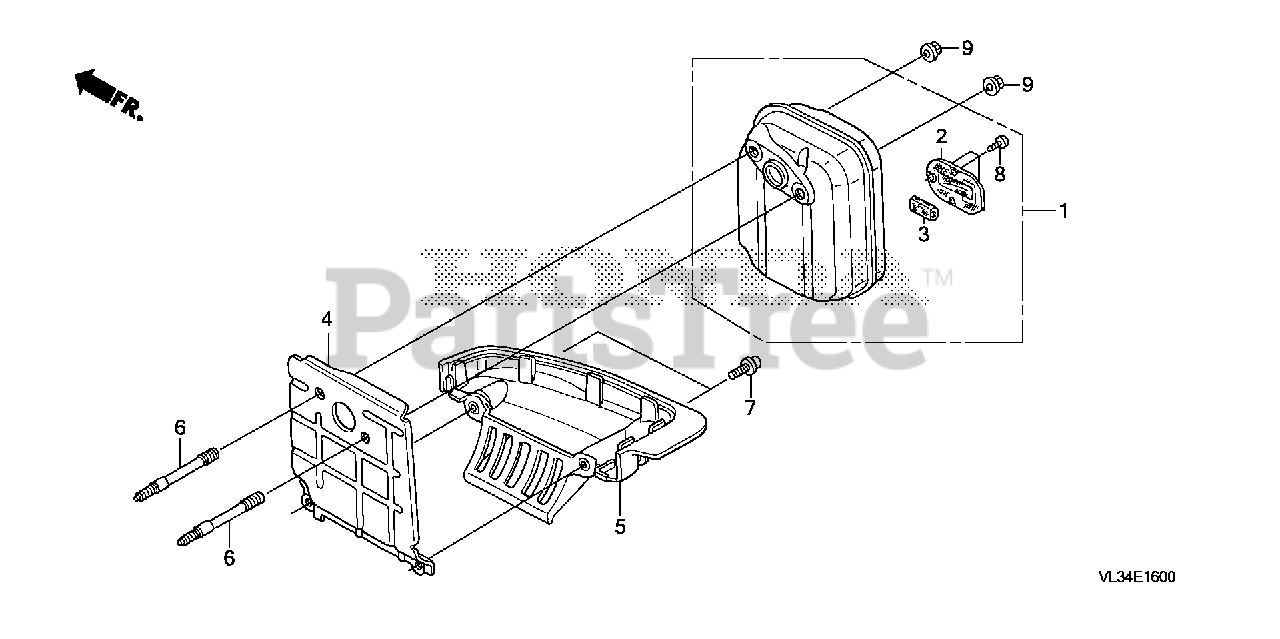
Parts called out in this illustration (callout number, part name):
1	MUFFLER (ARRESTER)
2	ARRESTER, SPARK
3	FILTER, EX.
4	GUIDE, AIR
5	GUIDE, AIR (LOWER)
6	BOLT, STUD (5X56.5)
7	BOLT, SOCKET (5X16)
8	SCREW, TAPPING (4X6) (TO INSTALL OPTIONAL SPARK ARRESTER)
9	NUT, SELF-LOCK (5MM)
